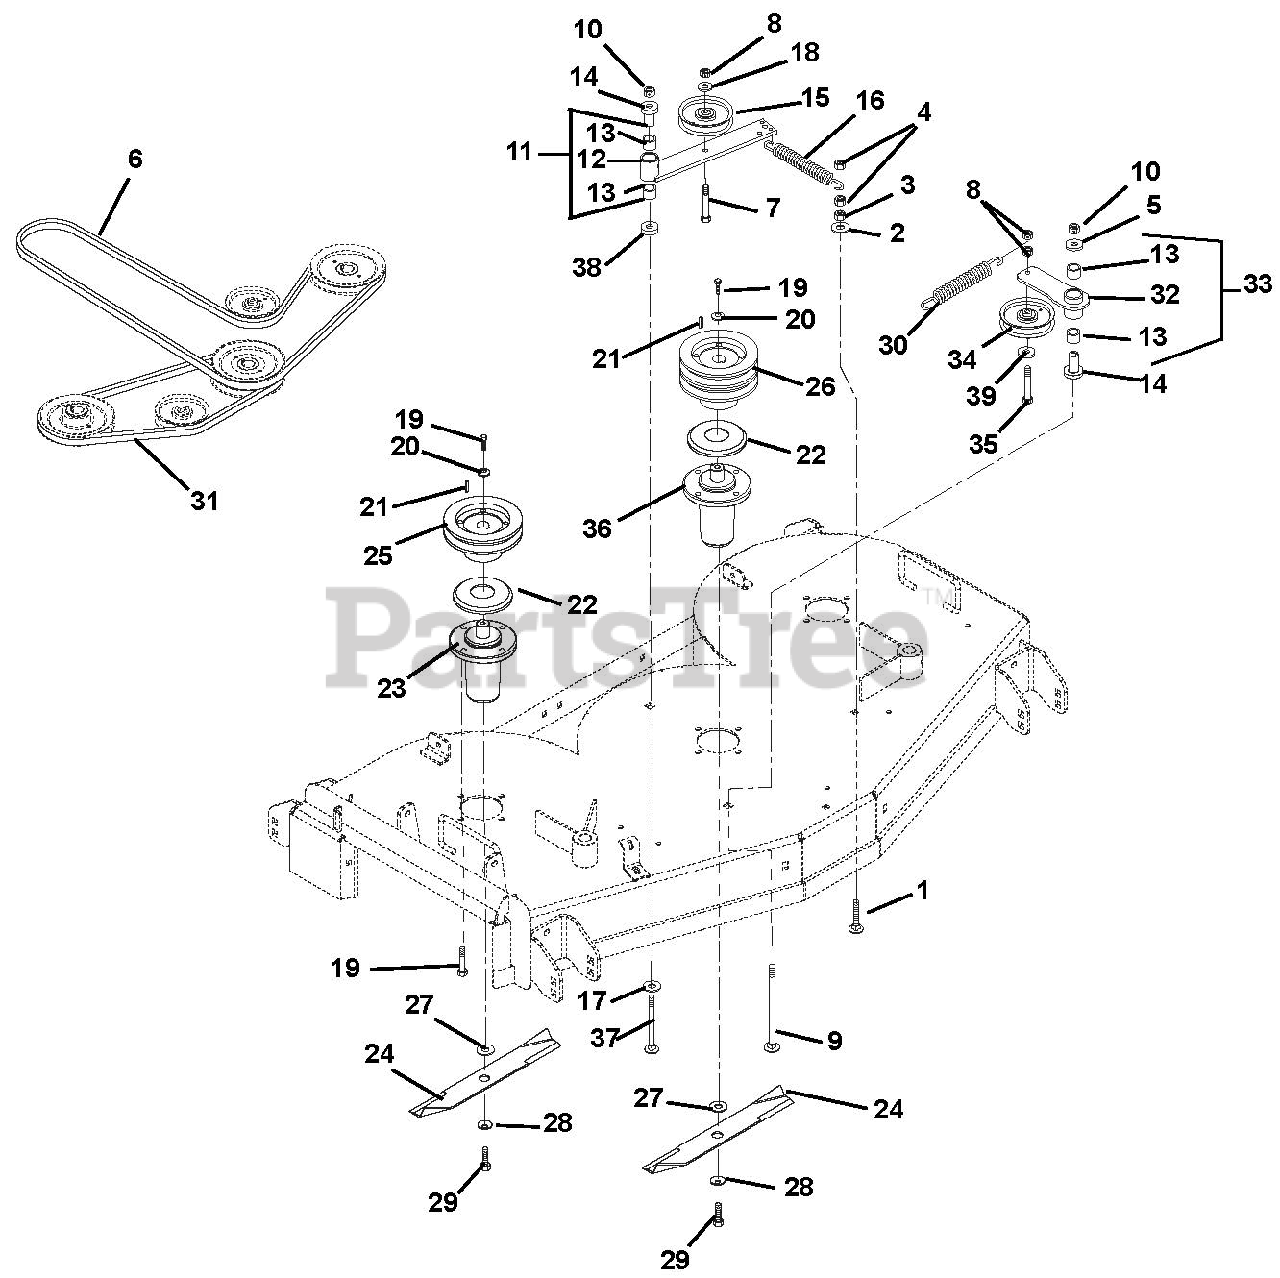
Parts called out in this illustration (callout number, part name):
1	Bolt, Round Head Square Neck .38-16 x 1.50 Grade 5
2	Washer, Locking .38 x .094 Regular
3	Nut, Hex .38-16
4	Nut, Locking-Center .38-16
5	Washer, Flat-Steel .531 x 1.25 x .10
6	V-Belt B-Section 39.38 x .65
7	Bolt, Round Head Square Neck .38-16 x 3.00 Grade 5
8	Nut, Locking-Center .38-16
9	Bolt, Round Head Square Neck .50-13 x 3.50 Grade 5
10	Nut, Locking-Center .50-13
11	Assembly, Idler Pivot Arm
12	Weldment, Idler Pivot Arm
13	Bearing, 1.00 x 1.12 x .75
14	Bearing, Pedestal Powdered Metal
15	Idler, Flat 4.00 x .38, 2.00 W
16	Spring, Extension
17	Washer, Flat-Steel .755 x 1.375 x .062
18	Seal, Idler Bearing
19	Bolt, Hex .38-16 x 1.00 Grade 8
20	Washer, Flat-Steel .406 x 1.50 x .245
21	Key, Square .25 x .25 x 1.00 RC 40-50
22	Slinger-Dust
23	Assembly, Maintenance Free Spindle
24	Blade, Mower
25	Pulley
26	Sheave, Double, 5.25
27	Washer, Flat .64 x 1.81 x .250
28	Washer, Bellville .63 x 1.625 x .14
29	Bolt, Hex .62-18 x 1.75 Grade 8
30	Spring, Extension
31	V-Belt 5L-Section 49.97 x .672
32	Arm, Idler Pivot
33	Asm, Idler Pivot Arm
34	V-Idler, 4.00 x .38
35	Bolt, Hex .38-16 x 2.25 Grade 5
36	Spindle Assembly
37	Bolt, Round Head Square Neck .50-13 x 3.75
38	Washer, Flat-Steel .515 x 1.625 x .25
39	Washer, Flat-Steel .406 x .812 x .065
